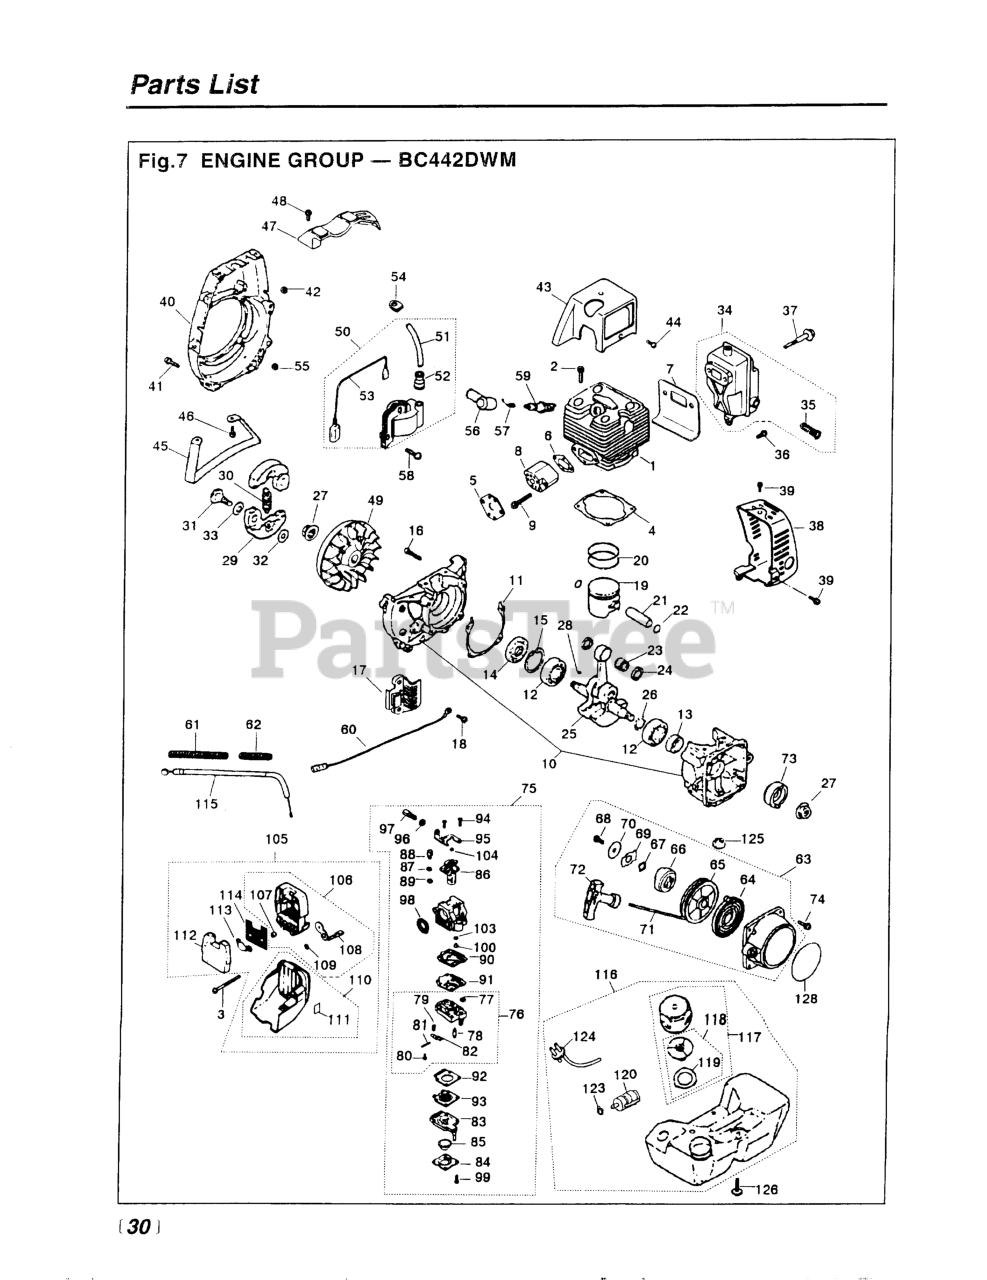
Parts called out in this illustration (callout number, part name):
1	CYLINDER (RPLS -12112)
2	BOLT M5 x 20 (RPLS -12280)
8	INSULATOR (RPLS -13162)
9	SCREW, M5 X 40
10	CRANKCASE COMPLETE
13	SEAL, OIL - STARTER SIDE
15	RING, SNAP, M35 X 1.5
16	BOLT, M5 X 30
17	GUARD (RPLS-21310)
18	SCREW,M5 X 14 (RPLS 1400-15510
19	PISTON
20	RING
21	PIN, PISTON
22	RING, SNAP
23	BEARING
24	WASHER (RPLS 1491-41510)
25	SHAFT (RPLS -42001)
26	SHIM (REPLACES 848-870-G000)
27	NUT, M10
28	KEY
29	SHOE (RPLS -51112)
31	SCREW
32	WASHER
33	WASHER (USE -51241)
35	ARRESTER
36	SCREW, M5 X 12
37	BOLT
38	COVER
39	SCREW, M5 X 12
40	COVER, FAN (REPLACES -31111)
41	BOLT M5 x 20 (RPLS -12280)
43	COVER (RPLS -32110)
44	SCREW, M5 X 12
45	STAND
46	BOLT (REPLACES 01252-30514)
48	SCREW, M5X20 (RPLS.1400-75510)
50	COIL ASSEMBLY
52	CAP
54	GROMMET
57	SPRING
58	SCREW, M5X20 (RPLS.1400-75510)
62	TUBE (RPLS -72930)
64	SPRING (RPLS -75220)
66	DOG
67	WASHER
68	SCREW
69	RETAINER (RPLS 1861-75161)
70	WASHER
71	ROPE
72	KNOB
73	PULLEY (RPLS -75210)
74	SCREW, M5X20 (RPLS.1400-75510)
75	CARBURETOR ASSEMBLY
76	BODY, PUMP
78	VALVE, INLET
79	SPRING, METERING LEVER
80	SCREW, METERING LEVER PIN
81	PIN, METERING LEVER
82	LEVER
83	BODY, PURGE
84	COVER, PUMP
85	PUMP, PRIMING
86	VALVE ASSY
87	WASHER
88	SWIVEL
89	RING
90	GASKET, PUMP
91	DIAPHRAGM
92	GASKET, DIAPHRAGM
93	DIAPHRAGM (USE 4810-81260)
94	SCREW
96	NUT, CABLE ADJUSTER
98	RING, PACKING
99	SCREW
103	RING, O
105	CLEANER (USE -82003)
106	BODY ASSY (REPLACES -82101)
107	SLEEVE
110	COVER, AIR FILTER (RPLS -82201
111	LABEL
112	ELEMENT (RPLS -82310)
113	PLATE
115	CABLE COMPLETE
118	VALVE COMPLETE
119	PACKING (RPLS -85321)
120	FILTER ASSY
123	CLIP (REPLACES 2841-31280)
124	PIPE ASSY (RPLS -85800)
126	SCREW
128	LABEL, RECOIL(RPLS 1403-75411)
